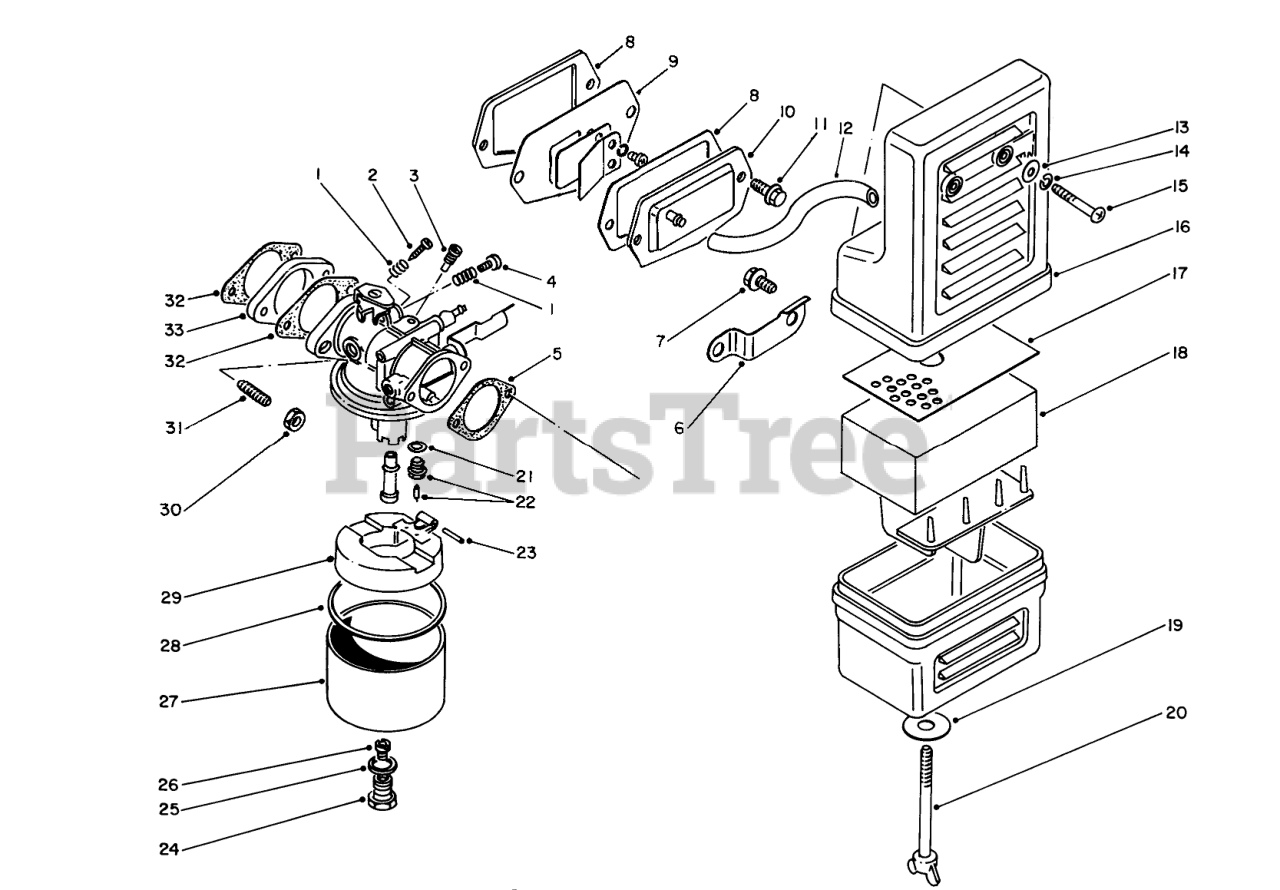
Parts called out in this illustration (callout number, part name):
1	Spring
2	ADJUSTER
3	Jet
4	Screw
5	AIR CLEANER GASKET
6	Bracket
8	Gasket
9	Reed Valve Assembly
13	WASHER
14	Washer
15	SCREW
16	Cleaner Assembly-Air (Incl. Ref. #17-20)
17	Holder
18	FILTER
19	WASHER
20	Bolt-Wing
21	GASKET
22	NEEDLE VALVE
25	Gasket
26	MAIN JET
27	Carburetor Assembly (Incl. Ref. #1-4, 21-26 & 28-29)
28	GASKET
29	FLOAT
31	Bolt-Stud
32	Gasket
33	INSULATOR
